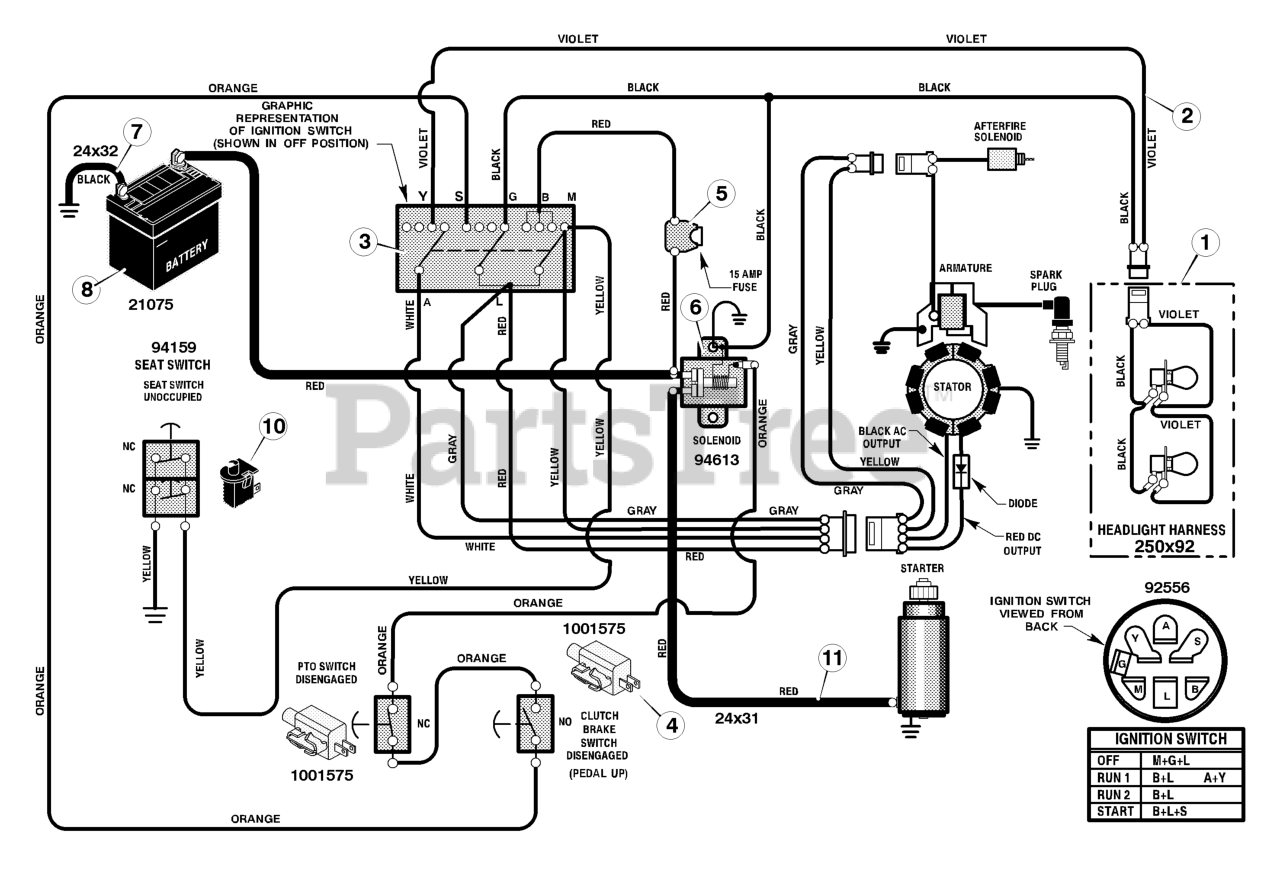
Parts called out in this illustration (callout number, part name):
1	Harness, Light Wire
2	Harness, Chassis Wire
3	Switch, Ignition
4	Switch, Limit
6	Solenoid
7	Cable, Battery Ground
8	Battery
10	Switch, Seat Sensor
